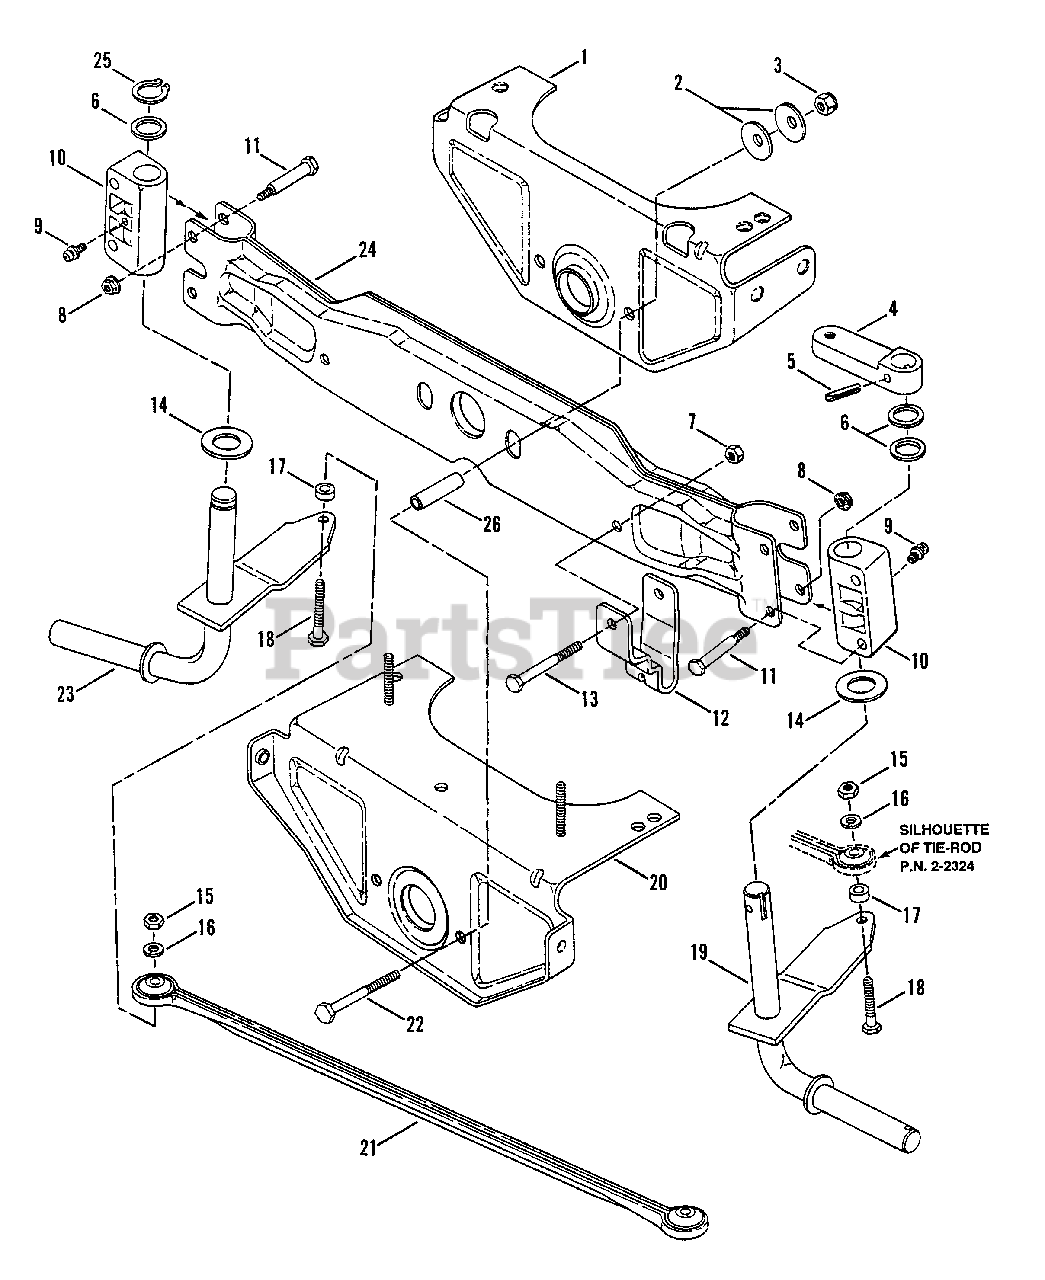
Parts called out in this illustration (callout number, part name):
1	BRACKET, Axle (Rear)
2	WASHER, Cone
3	NUT, 3/8-16 Nyloc
4	ARM, Steering
5	ROLL-PIN, 1/4 x 1 1/4"
6	WASHER, Shim
7	NUT, 5/16-18 Center Lock
8	NUT, 1/4-20 Hex Flange Top-Lock
9	LUBE FITTING, Straight (press-fit for .187 dia. Hole)
10	BEARING, Spindle
11	BOLT, 1/4-20 x 1 41/64" Shoulder
12	BRACKET, Deck Hanger
13	SCREW, 5/16-18x 21/2" Hex Head Cap
14	WASHER, Thrust
15	NUT, 3/8-16 Hex
16	WASHER, 3/8 Split Lock
17	SPACER, Tie-Rod
18	SCREW, 3/8-16 x 1 1/2" Hex Head Cap, Grade 5
19	SPINDLE ASSEMBLY, Left Hand, Long
19	SPINDLE ASSEMBLY, Left Hand, Short
20	BRACKET ASSEMBLY, Axle (Front)
21	TIE-ROD
22	BOLT, 3/8-16 x 3" Hex Head
23	SPINDLE ASSEMBLY, Right Hand, Long
23	SPINDLE ASSEMBLY, Right Hand, Short
24	AXLE, Front
25	RING, Retaining
26	SPACER
